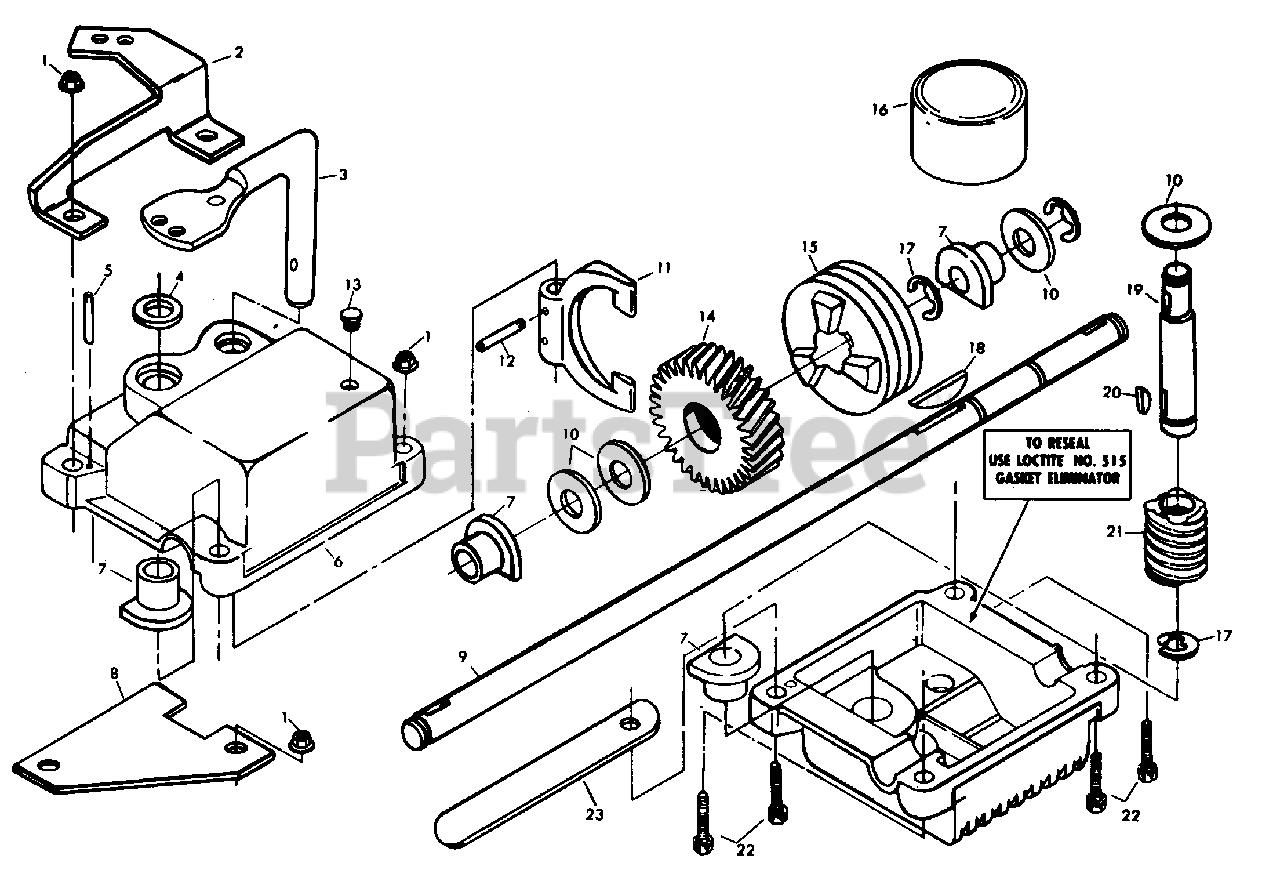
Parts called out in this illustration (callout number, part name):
1	Keps Locknut (AYP part number)
2	Adjusting Bracket (AYP part number)
3	Shifter Assembly (AYP part number)
5	Grooved Pin (AYP part number)
6	Gear Case Halves (AYP part number)
7	Bearing (AYP part number)
8	Spring Bracket (AYP part number)
9	Drive Shaft (AYP part number)
10	Hardened Washer (AYP part number)
11	Yoke Clutch (AYP part number)
12	Grooved Pin (AYP part number)
13	Plug (AYP part number)
14	Helical Gear (AYP part number)
15	Jaw Clutch (AYP part number)
16	Grease (AYP part number)
17	E-Ring (AYP part number)
18	Hi-Pro Key (AYP part number)
19	Worm Shaft (AYP part number)
20	Woodruff Key #3 (AYP part number)
21	Worm (AYP part number)
22	Hex Head Mach. Screw (AYP part number)
23	Identification Tag
